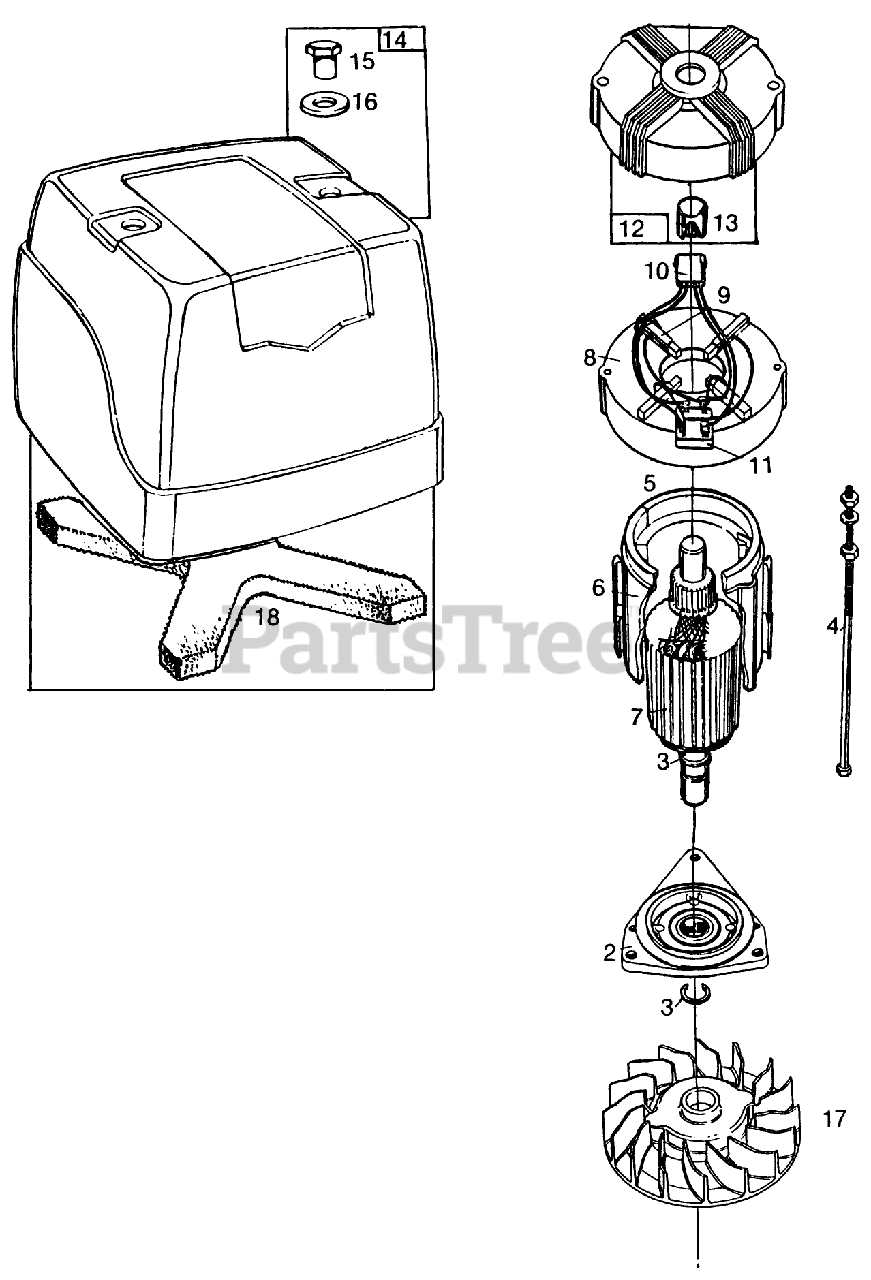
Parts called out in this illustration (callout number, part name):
2	Spacer
3	Ring-Retaining
4	Bolt-Thru (Includes Two Sets)
5	Housing Assembly
6	Insulator Group-Housing
7	Armature Group
8	Box-Brush
9	Brush Group (Includes Brush Holders and Retainers) Uses: 399187 Retainers (Includes 4 Parts)
10	Lead Group
11	Rectifier
12	End Cap-Brush
13	Bearing-Needle
14	Cover Group-Motor (Includes Hardware Filter)
15	Nut-Hex
16	Washer
18	Filter
